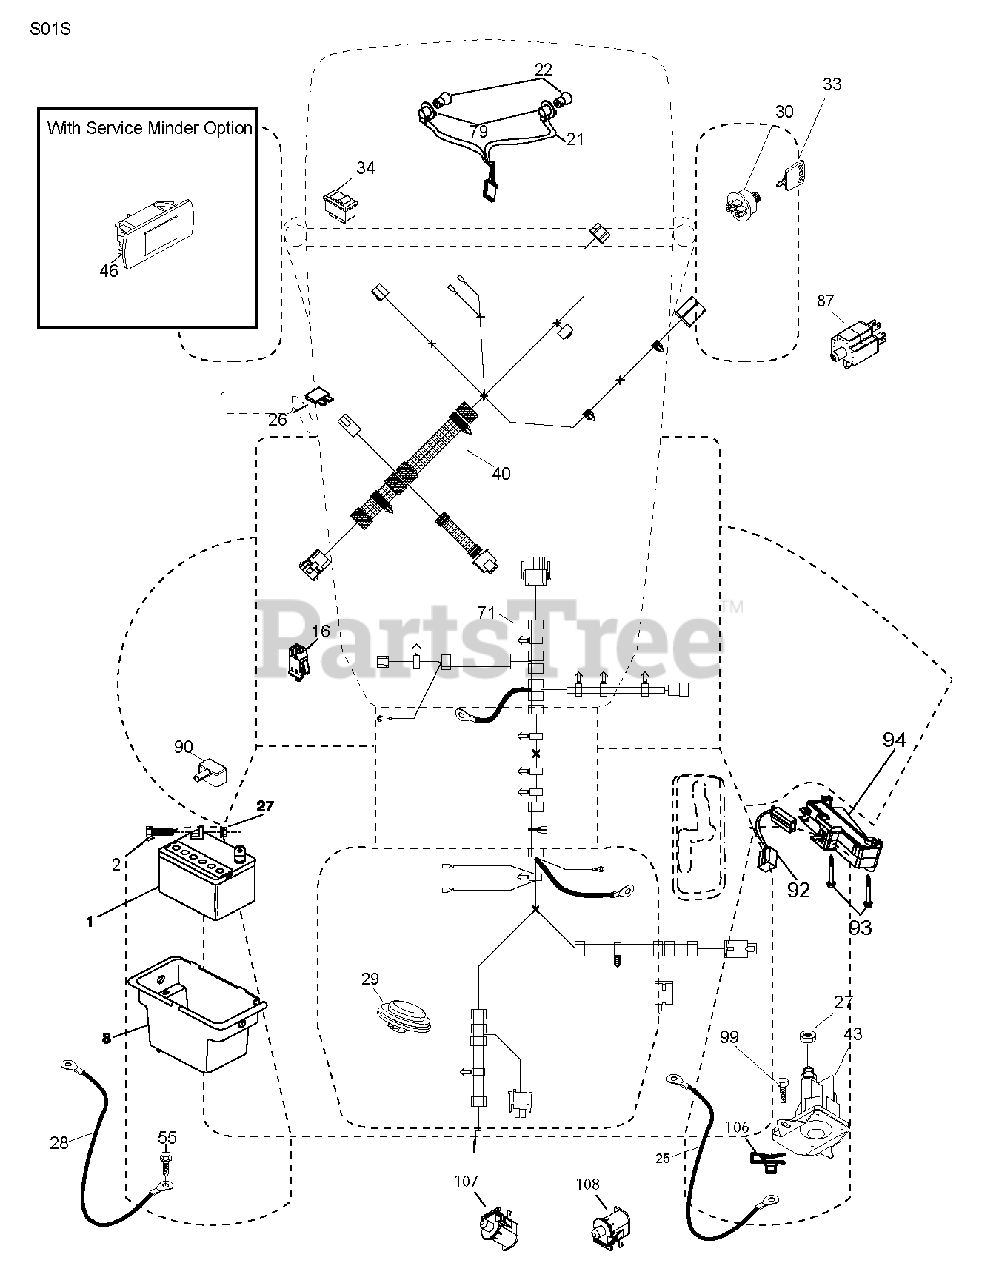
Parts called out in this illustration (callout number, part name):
1	REPL BY 532 12 38-99
8	BOX.BATTERY.LT/SRD
16	SWITCH INTERLOOK PUSH-IN
21	HARNESS.LIGHT W/4152J BULBS
25	CABLE.BATTERY.20.RED.8 AWG
27	NUT
28	Battery Ground Cable, Rear 8 Ga
29	SWITCH.SEAT.DELTA.OPC.
30	SWITCH.IGN.DELTA.W.LGH.ROS
33	KEY.CHAIN.BLISTER.PACK.GEN.INT
40	HARNESS.ELECTRICAL.DASH.SRD
43	SOLENOID.W/BRASS.PLUNG
55	SCREW 5/16"
71	HARNESS.ELECTRIC.CHASSIS.SRD
79	BULB HOLDER ASM.
87	Railmount Switch, No-Nc-Nc
90	COVER.TERMINAL.BATTERY
92	HARNESS.PIGTAIL.CONSLE
93	SCREW.PLASTITE
94	MODULE.REVERSE.ROS
99	SCREW HEXWSHR 1/4-20X3/4
107	Snapmount Switch, No #2
108	SWITCH.SNAPMOUNT.NC
